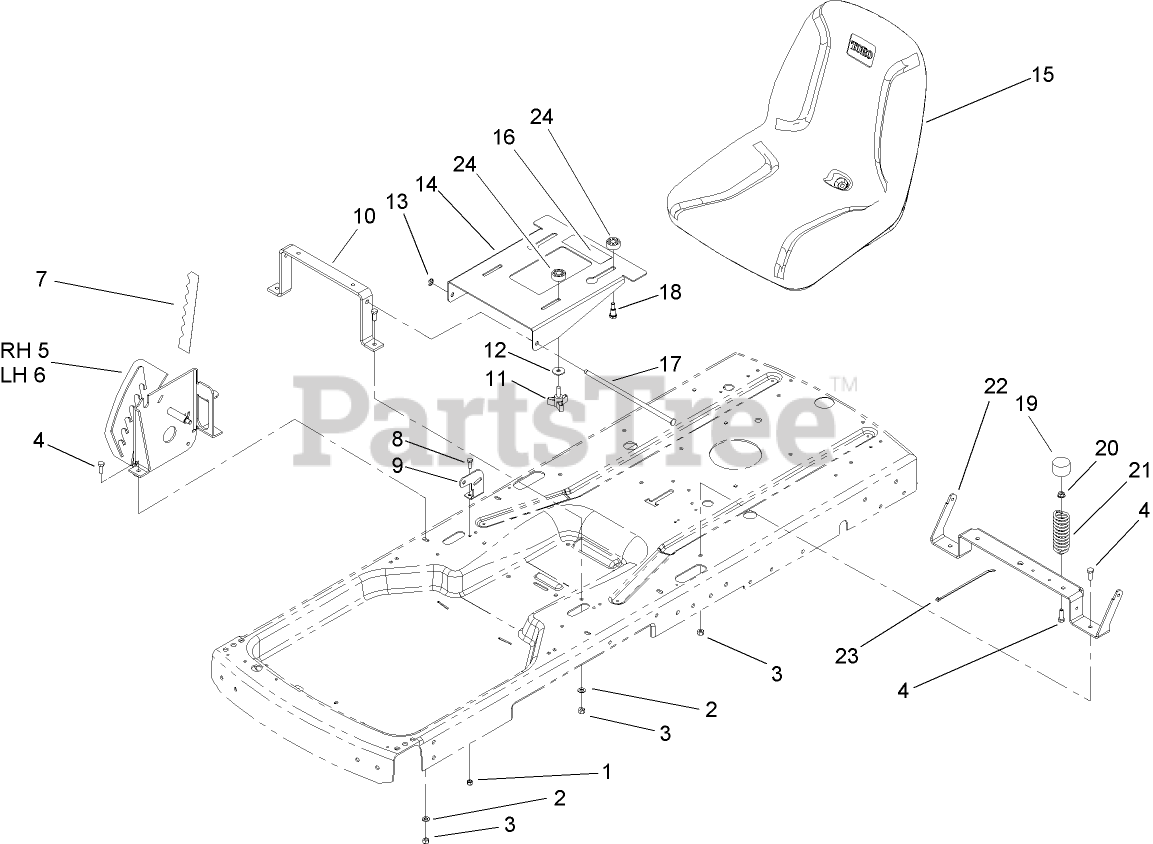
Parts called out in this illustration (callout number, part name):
1	NUT-LOCK, NI
2	WASHER-PLAIN
3	NUT-LOCK, NI
4	SCREW-HH
5	RH PLATE ASM
6	LH PLATE ASM
7	DECAL-HOC
8	SCREW-HH
9	BRACKET-BELLCRANK
10	BRACE-SEAT, FRONT
12	WASHER-PIVOT
13	E-RING
14	BRACKET-SEAT
15	SEAT
16	DECAL-SERVICE, CE
17	PIN-PIVOT
18	SCREW-SHOULDER
19	CAP-PROTECTOR
20	NUT-HF
21	SPRING-COMPRESSION
22	BRACE-SEAT, REAR
23	TIE-CABLE
24	SPACER-NYLON
